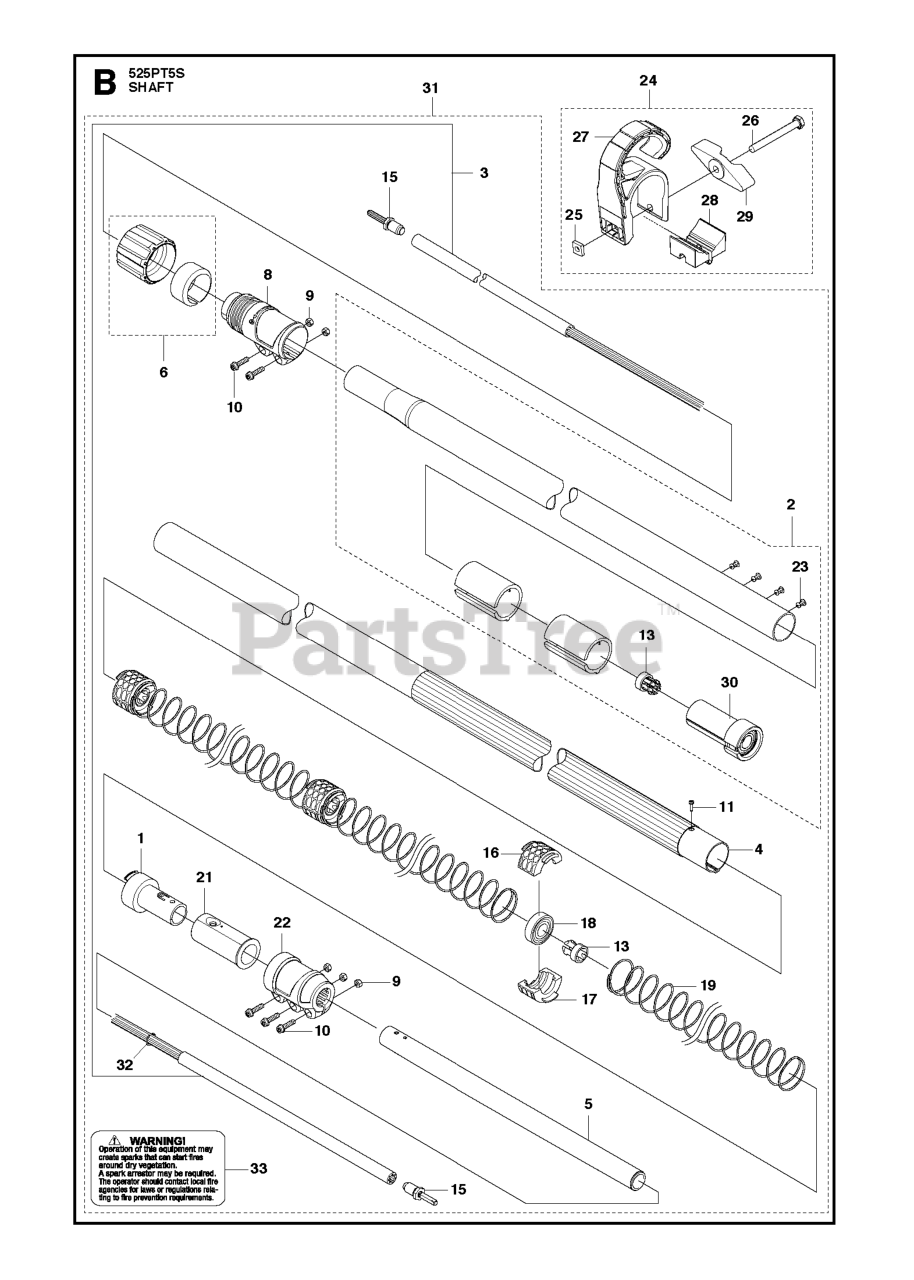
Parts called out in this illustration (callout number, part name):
1	BEARING SLEEVE
2	TUBE UPPER ASSY 525
3	DRIVE SHAFT ASSY
4	FRAME TUBE
5	TUBE
6	NUT
7	RING
8	CLAMPING SLEEVE
9	NUT
10	SCREW
11	SCREW
13	SLIDING SHOE
15	ADAPTER
16	BEARING HOUSING
17	BEARING HOUSING
18	BALL BEARING
19	SPRING
21	SLEEVE
22	CLAMPING SLEEVE
23	RIVET
24	LOOP
25	NUT
26	SCREW M6X55
27	LOOP
28	SPACING BLOCK
29	HANDLE
30	BEARING SLEEVE
31	TUBE DRVESHAFT ASSY TELESCOPIC
32	SNAP RING
